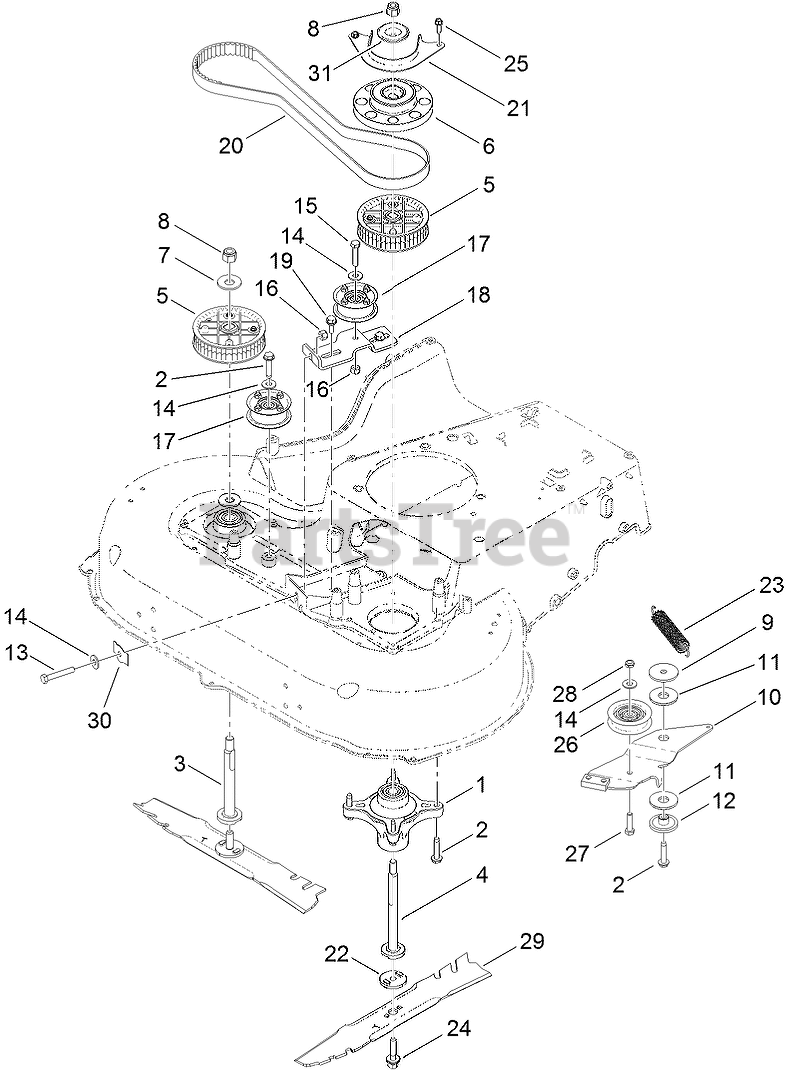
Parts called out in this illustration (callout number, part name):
1	SPINDLE ASM
3	SHAFT-SPINDLE
4	SHAFT-SPINDLE
5	SPROCKET
6	PULLEY-BRAKE, SPINDLE
7	WASHER-SPRING
8	NUT-HEX
9	WASHER-REBOUND
10	ARM-BRAKE
11	WASHER-FRICTION, COMPOSITE
12	SPACER
13	BOLT-TAP, HH
14	WASHER-FLAT
15	SCREW-HH
16	NUT-LOCK, NI
17	PULLEY
18	BRACKET-IDLER
19	SCREW-SHOULDER, HHF
20	BELT-SYNCHRONOUS
21	GUIDE-BELT, SPINDLE
22	ADAPTER-BLADE
23	SPRING-EXTENSION, BRAKE
24	BOLT-BLADE
25	SCREW-HWHTF
26	PULLEY-IDLER
27	SCREW-HH
28	NUT-LOCK, NI
29	BLADE-ATOMIC, 15.4 INCH
30	SPRING-FLAT
31	WASHER-CUP
